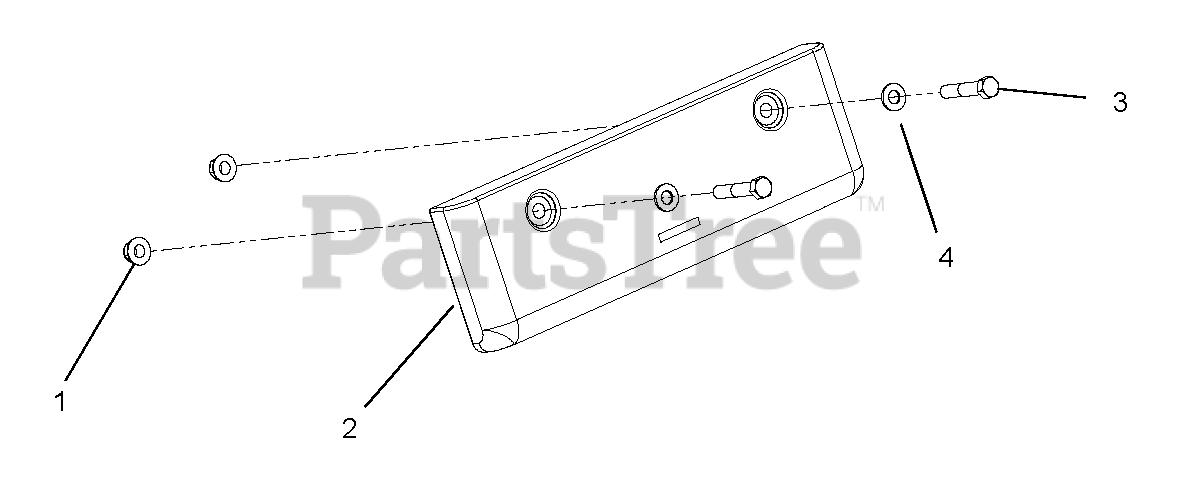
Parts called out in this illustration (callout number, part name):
1	@NUT-LK-NYL-FLG .50-13 YWZC
2	WEIGHT, CAST IRON
3	@BLT-HEX .50-13X2.75 GR5 YWZC
4	@WSHR-FL-STL.531X1.06X.095YWZC
